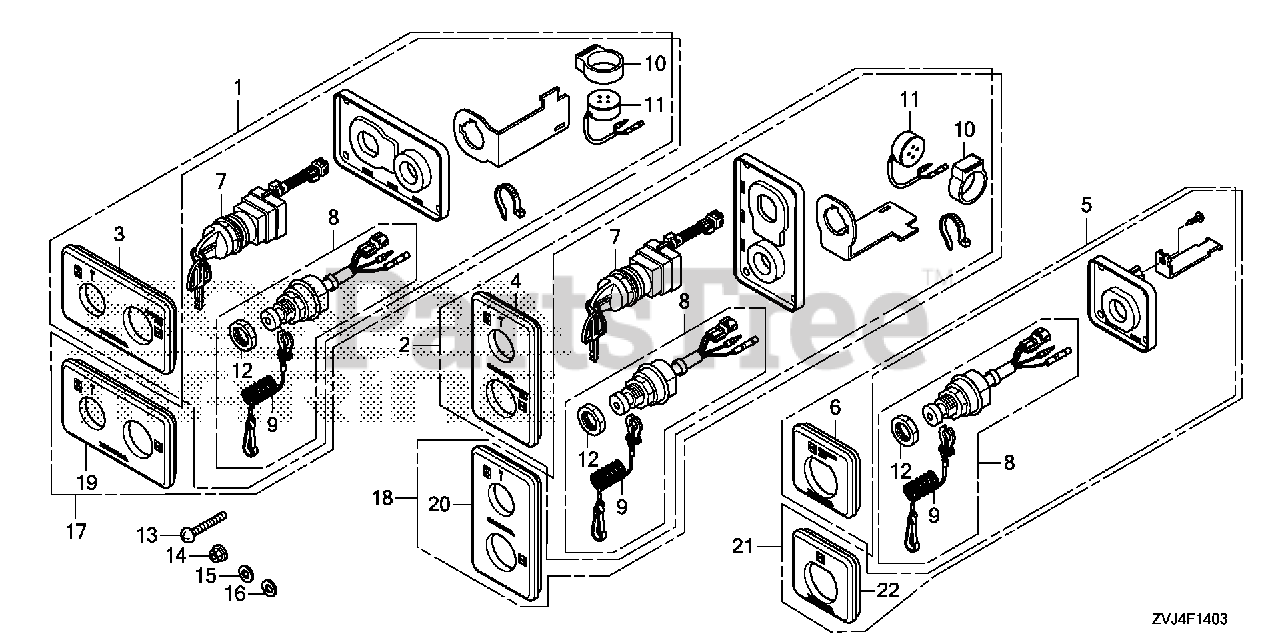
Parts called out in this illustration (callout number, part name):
1	PANEL ASSY., KEY SWITCH (START)
2	PANEL ASSY., KEY SWITCH (START)
3	PANEL, KEY SWITCH (START)
4	PANEL, KEY SWITCH (START)
7	SWITCH ASSY., COMBINATION (START)
8	SWITCH ASSY., EMERGENCY STOP
9	WIRE, EMERGENCY
10	SUSPENSION, AUDIBLE PILOT
11	BUZZER, WARNING
13	SCREW, PAN (5X40)
14	NUT, FLANGE (5MM)
15	WASHER, PLAIN (5MM)
16	WASHER, SPRING (5MM)
17	PANEL ASSY., KEY SWITCH (START)
18	PANEL ASSY., KEY SWITCH (START)
19	PANEL, KEY SWITCH (START)
20	PANEL, KEY SWITCH (START)
